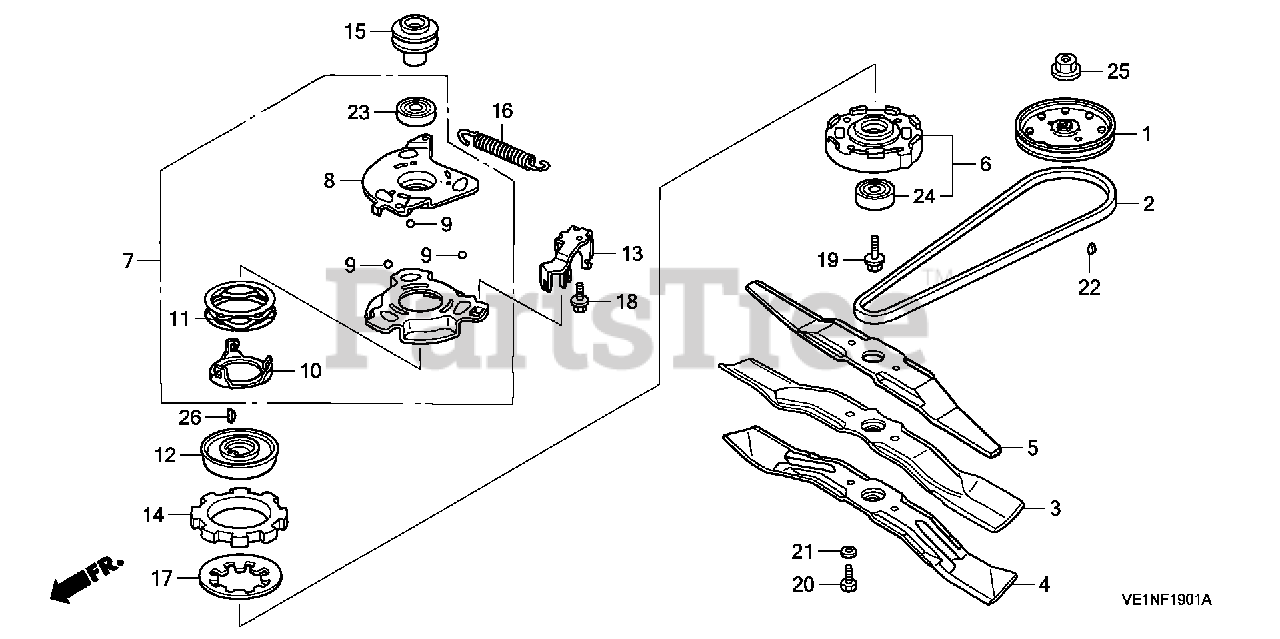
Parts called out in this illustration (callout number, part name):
1	PULLEY, DRIVEN
2	V-BELT (3L-36.9)
3	BLADE, ROTARY (BAGGING)
4	BLADE, ROTARY
4	BLADE, ROTARY (PCD=88MM)
5	BLADE, ROTARY (UPPER) (PCD=88MM)
6	HOLDER ASSY., BLADE
7	PLATE ASSY., BALL CONTROL
8	PLATE, BALL CONTROL
9	BALL, STEEL
10	PLATE, SPRING HOOK
11	SPRING, BALL PLATE
12	DISK, DRIVE
13	HOOK, RETURN SPRING
14	DISK, DRIVEN
15	PULLEY, DRIVE
16	SPRING, CLUTCH RETURN
16	SPRING ASSY., CLUTCH RETURN
17	SPRING, CLUTCH
18	BOLT, FLANGE (6X14) (CT200)
19	BOLT, FLANGE (10X24)
20	BOLT, HEX. (10X20)
21	WASHER, SPRING (10MM)
22	KEY, WOODRUFF
23	BEARING, RADIAL BALL (6006) (SST)
24	BEARING, RADIAL BALL (6204)
25	NUT, FLANGE (10MM)
26	KEY, WOODRUFF (16X15)
